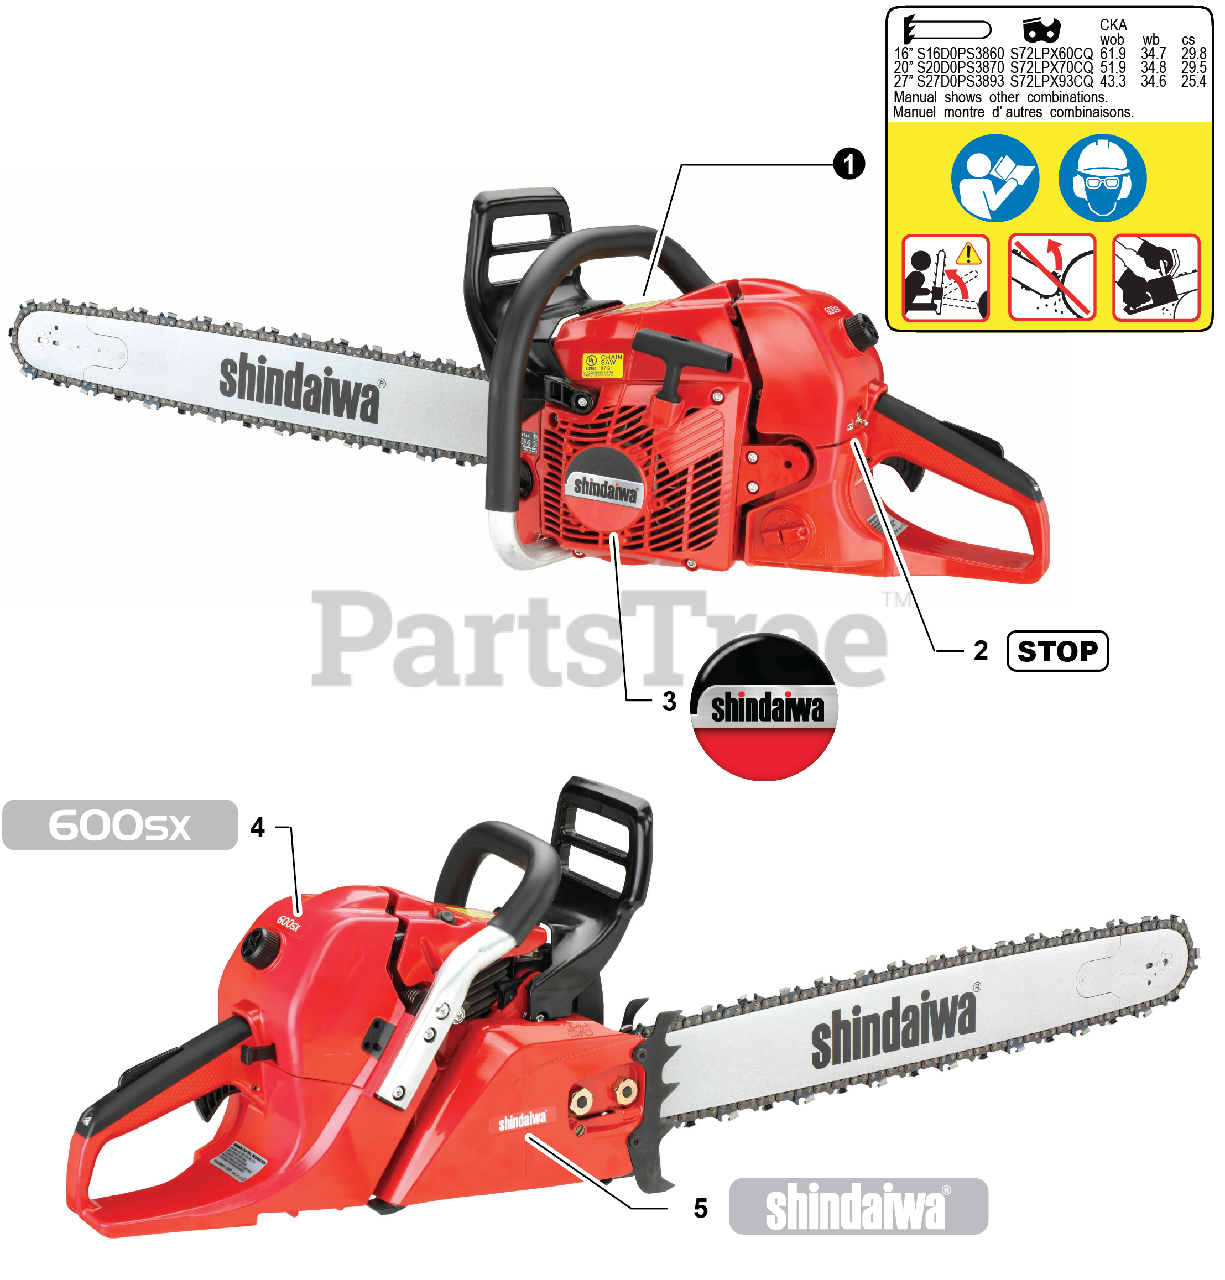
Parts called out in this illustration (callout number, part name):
1	LABEL, CAUTION
2	LABEL, STOP
3	LABEL, STARTER - SHINDAIWA
4	LABEL - MODEL 600SX
5	LABEL - SHINDAIWA
